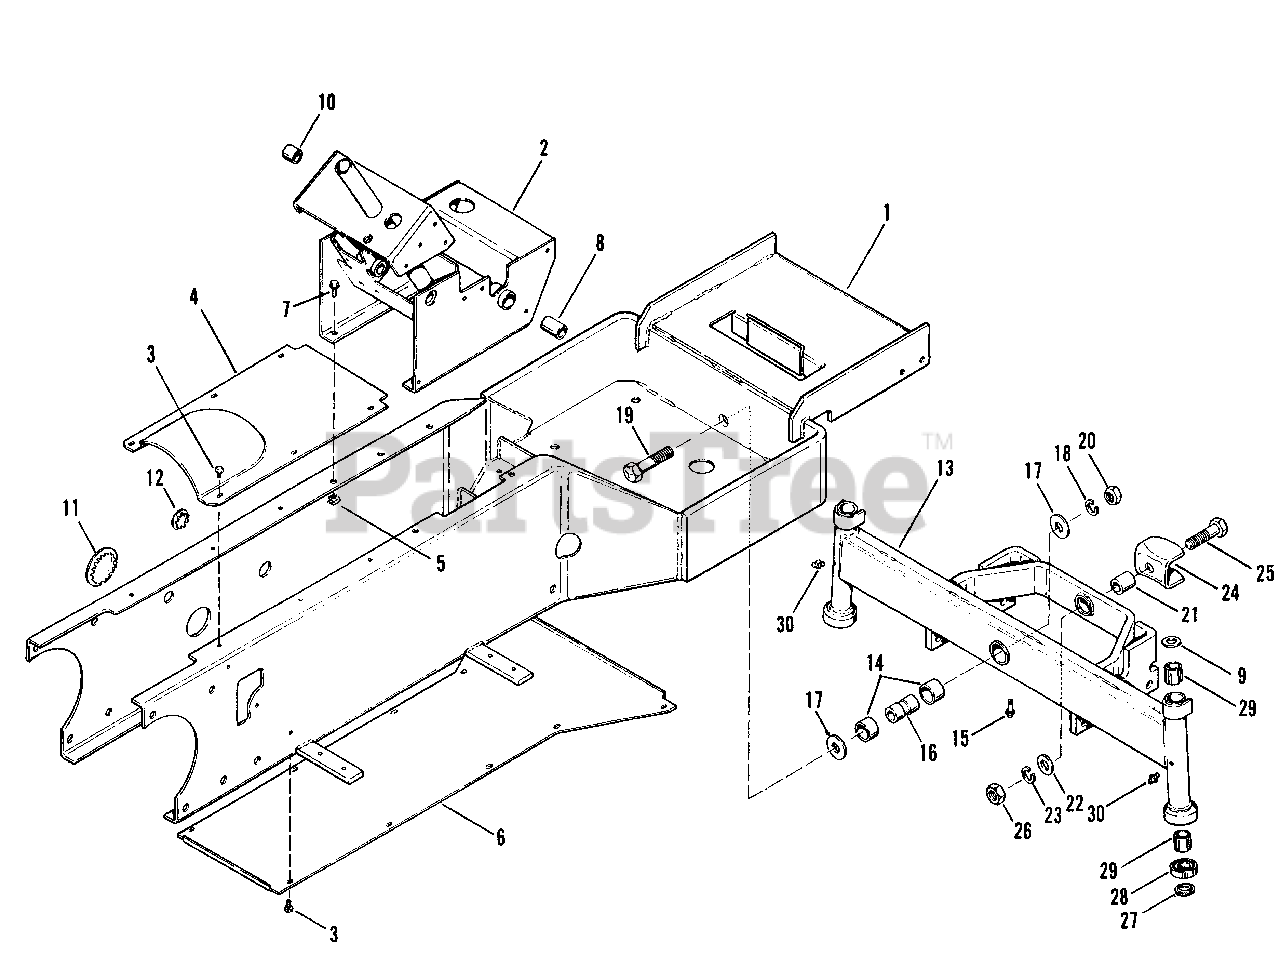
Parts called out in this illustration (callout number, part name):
1	Frame Assembly
2	Support Assembly
3	Washer Hd. Screw, 1/4"-20 x 3/8" lg.
4	Top Cover
5	Tinnerman Nut
6	Bottom Cover
7	Washer Hd. Screw, 5/16"-12 x 7/8" lg.
8	Bushing Sleeve
9	Thrust Washer
10	Bearing Sleeve
11	Hole Plug
12	Hole Plug
13	Axle Assembly
14	Axle Bushing
15	Grease Fitting
16	Axle Space
17	Thrust Washer
18	Lock Washer, 5/8"
19	Hex Capscrew, 5/8"-11 x 3-1/2" lg.
20	Hex Nut, 5/8"-11
21	Reach Bushing
22	Plain Washer, 5/8"
23	Lock Washer, 5/8"
25	Bolt, 5/8"-11 x 2-1/4" lg.
26	Hex Nut, 5/8"-11
27	Bearing Spacer
28	Thrust Bearing
29	Spindle Bushing
30	Grease Fitting
